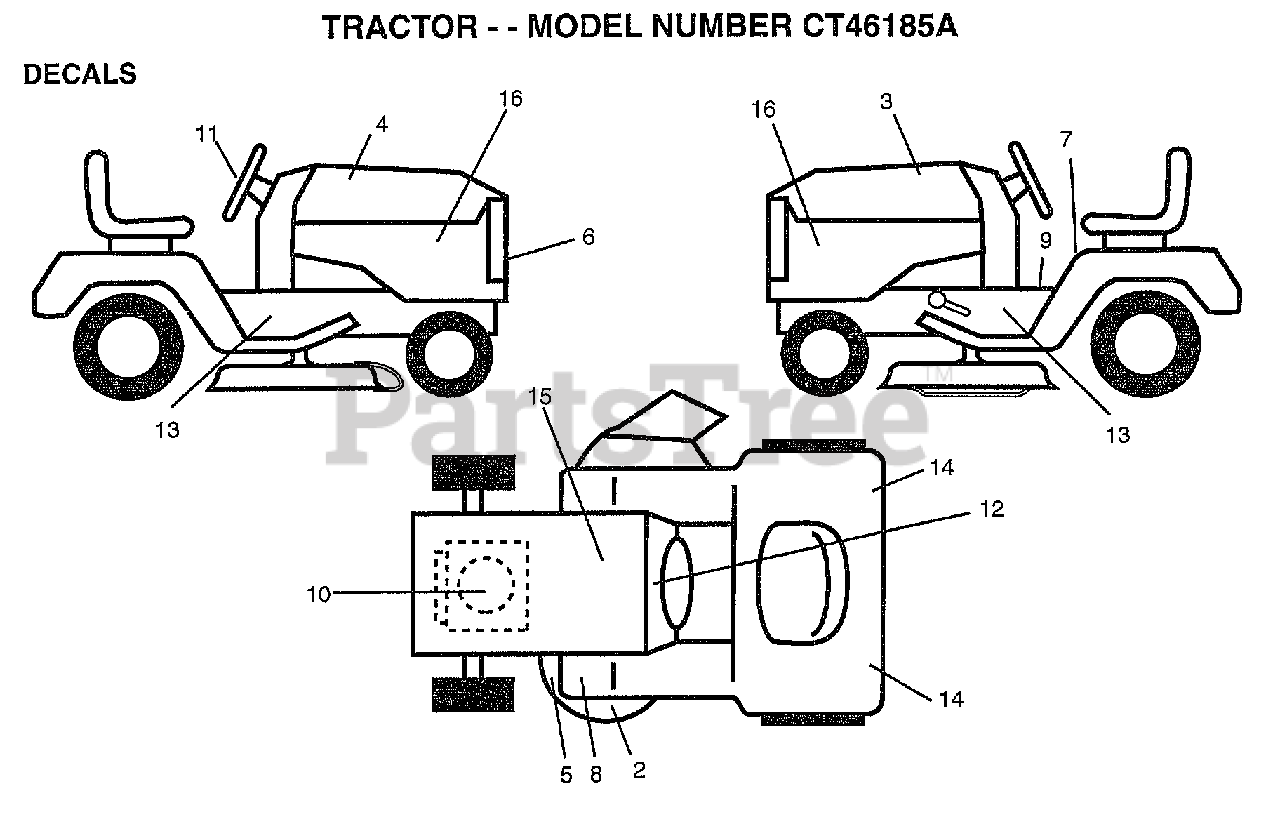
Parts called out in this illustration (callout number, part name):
2	"DECAL,ENVIRO DECK"
3	DECAL.HOOD.LH
4	DECAL.HOOD.RH
6	DECAL GRILLE
7	"DECAL DANGER,FEND"
9	DECAL BRAK PARK
10	DECAL, HP, ENGINE
11	DECAL INST STG WH
12	"DECAL-OPER,GEAR D"
13	DECAL CHASSIS
14	REFLECTOR-TAIL YT
15	DECAL.BATRY.3-3908
16	"DECAL PANEL,SIDE"
